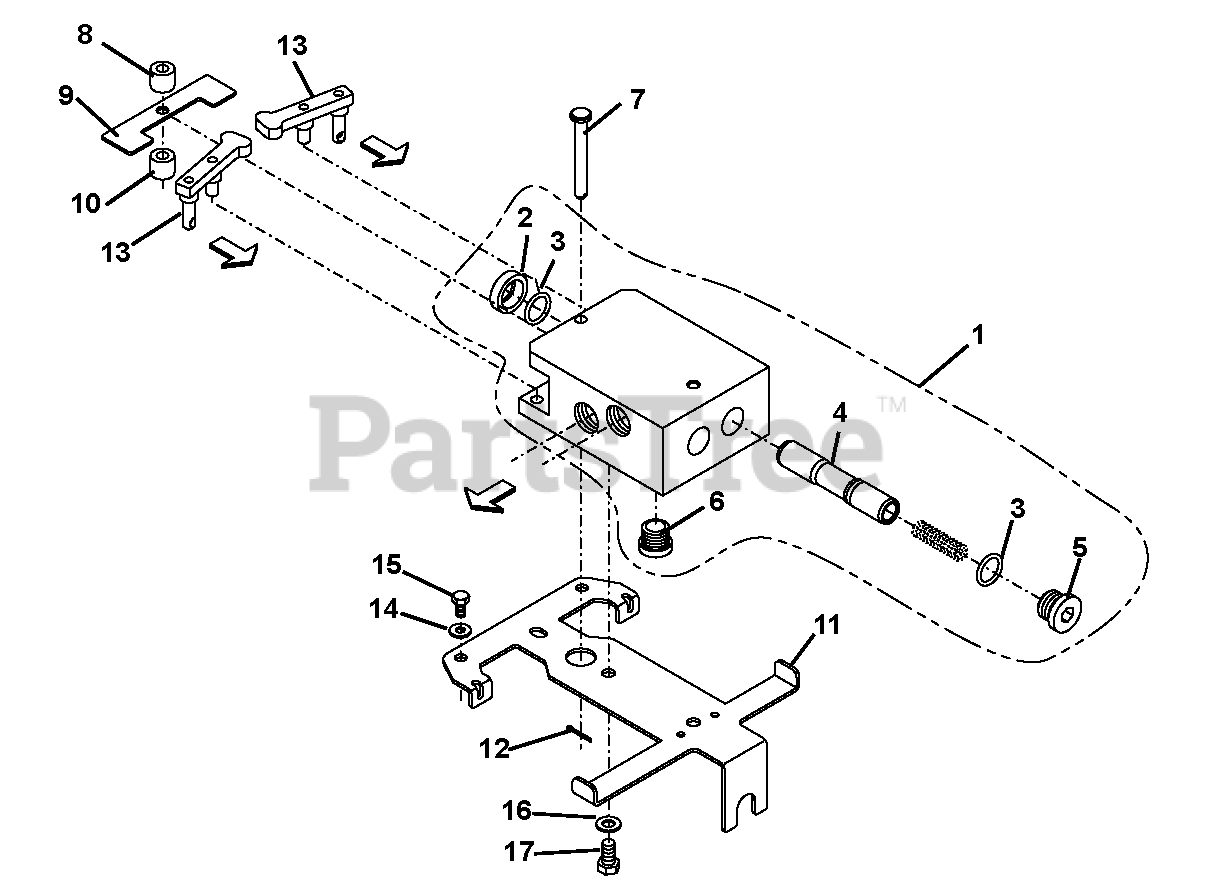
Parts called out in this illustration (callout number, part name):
1	Valve Steering (Includes items 2 - 6)
3	O-Ring, 17,86 x 2,62
4	Tappet Steeri
5	Drain Plug
6	Drain Plug
7	Bolt, 8 x 65
11	Plate, Support
12	Pin, Cotter, 2 x 16
14	Washer, M6
15	Hex Bolt, Metric 6 x 16
16	Washer, M8
17	Bolt, Hex, Metric 8 x 16
